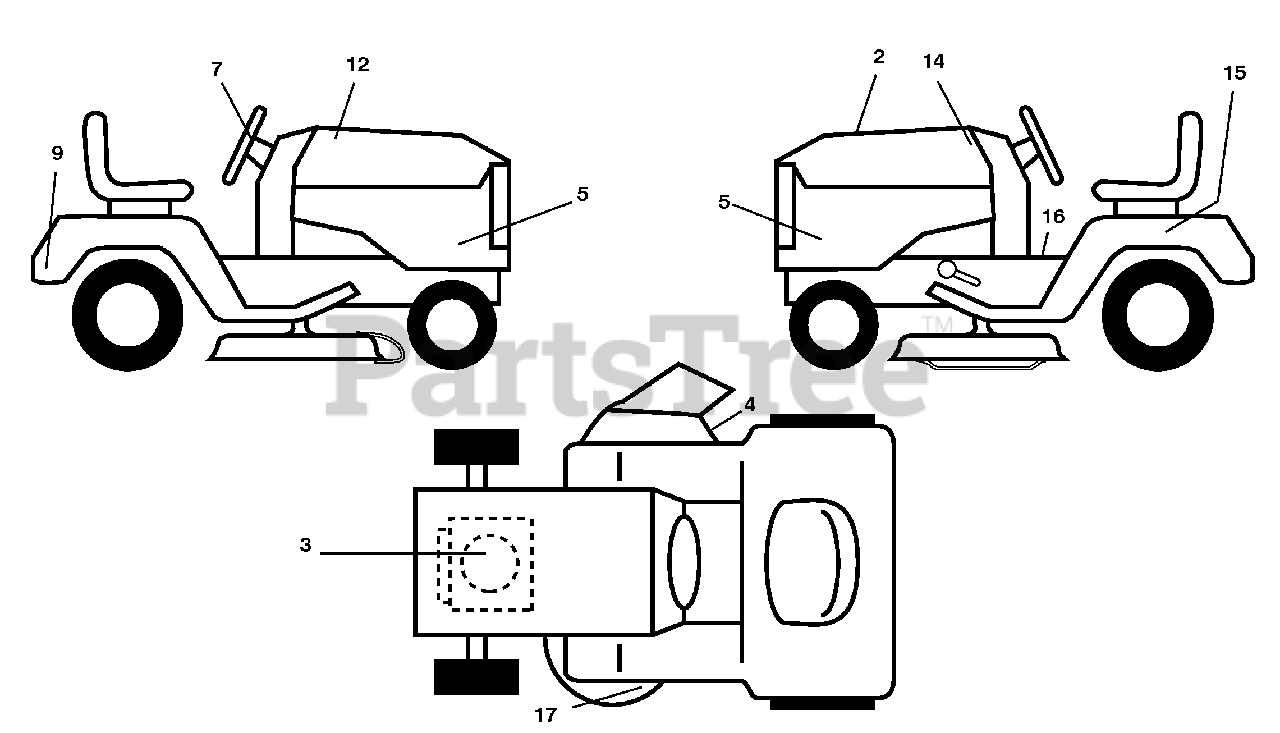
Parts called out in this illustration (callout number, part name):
2	Decal, Replacement
3	Decal, Engine HP
4	Decal, Warning
5	Decal, SDPNL
7	Decal, Ins Str Wh
9	Decal, Fender
12	Decal, Hood RH
14	Decal, Hood LH
15	Decal, Caution, Battery
16	Decal, Fender Warning Eng/Fr
17	Decal, V-Belt Sch.
17	Decal, Handle Lft Height Adj.
17	Manual, Operator's E&F
17	Manual, Parts E&F
